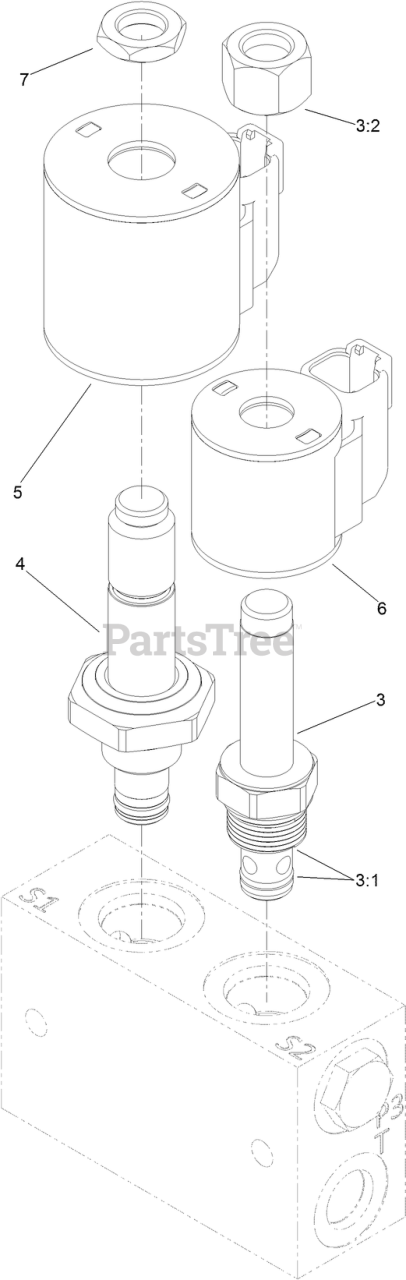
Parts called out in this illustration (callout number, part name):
3	VALVE-SOLENOID
3:1	SEAL KIT
3:2	NUT-SOLENOID
4	VALVE-SOLENOID
5	COIL-12V
7	NUT-COIL
